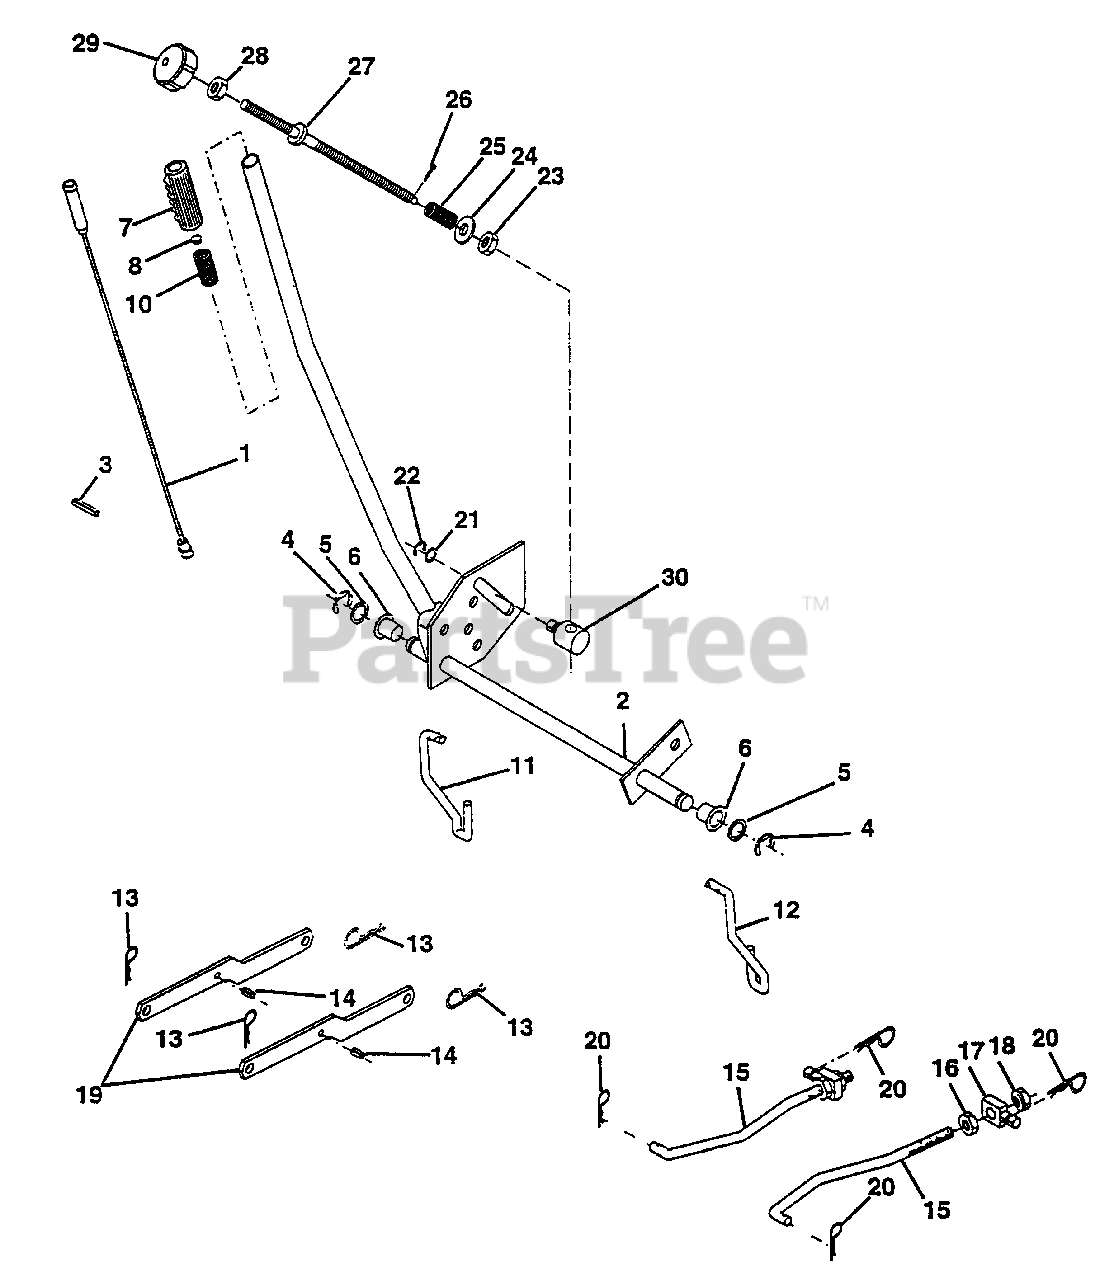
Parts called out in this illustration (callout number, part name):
1	Wire Asm Inner W/plunger 20 56
2	Shaft Asm Lift RH w/Inf W/T
3	Pin Groove 1 500 Zinc
4	B Ring #5133-62
5	Washer 21/32 X 7/8 X 16 Ga
6	Bearing Nylon Blk 629 Id
7	Grip Handle Fluted Blk
8	Button Plunger Black
10	Spring Cprsn 3 750 Oiled
11	Link Lift LH Fixed Length
12	Link Lift RH Fixed Length
13	Retainer Spring
14	Pin Roll SLT 5/16 X 1 25 Blk 0
15	Link Front
16	Nut Jam Hex 1/2-13 Unc
17	Trunnion Blk Zinc
18	Nut Lock W/wsh 1/2-13unc
19	Arm Suspension Rear
20	Retainer Spring
21	Washer 15/32 X 3/4 X 16 Ga
22	Ring Klip #t5304-37
23	Nut Special
24	Washer 13/32 X 5/8.X 16 Ga
25	Spring 2-1/8"
26	Pin Cotter 3/32 X 1/2
27	Rod Adj Lift Zinc 9 00 Wrk Lg
28	Nut Hex Jam 3/8-16 Unc
29	Knob Inf 3/8-16 Unc Blk W/sym
30	Trunnion Dp Stop Dbl Thds PLT
